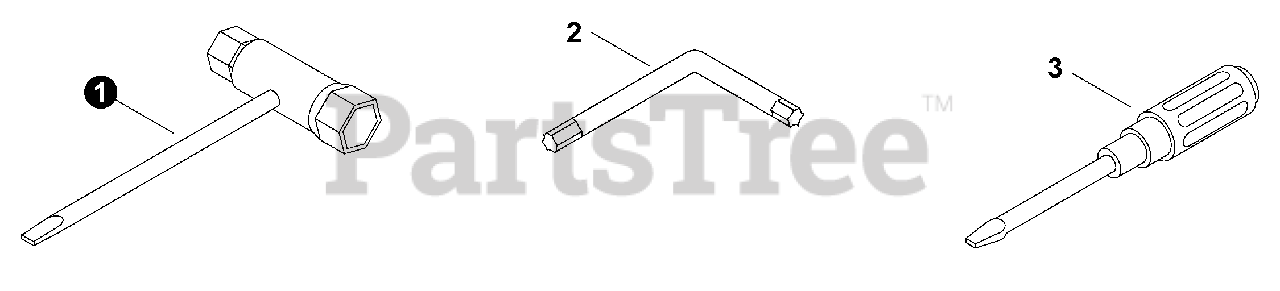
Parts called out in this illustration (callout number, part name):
1	T-WRENCH 13×19 L= 180
2	WRENCH, T27
3	SCREWDRIVER, PHILLIPS
